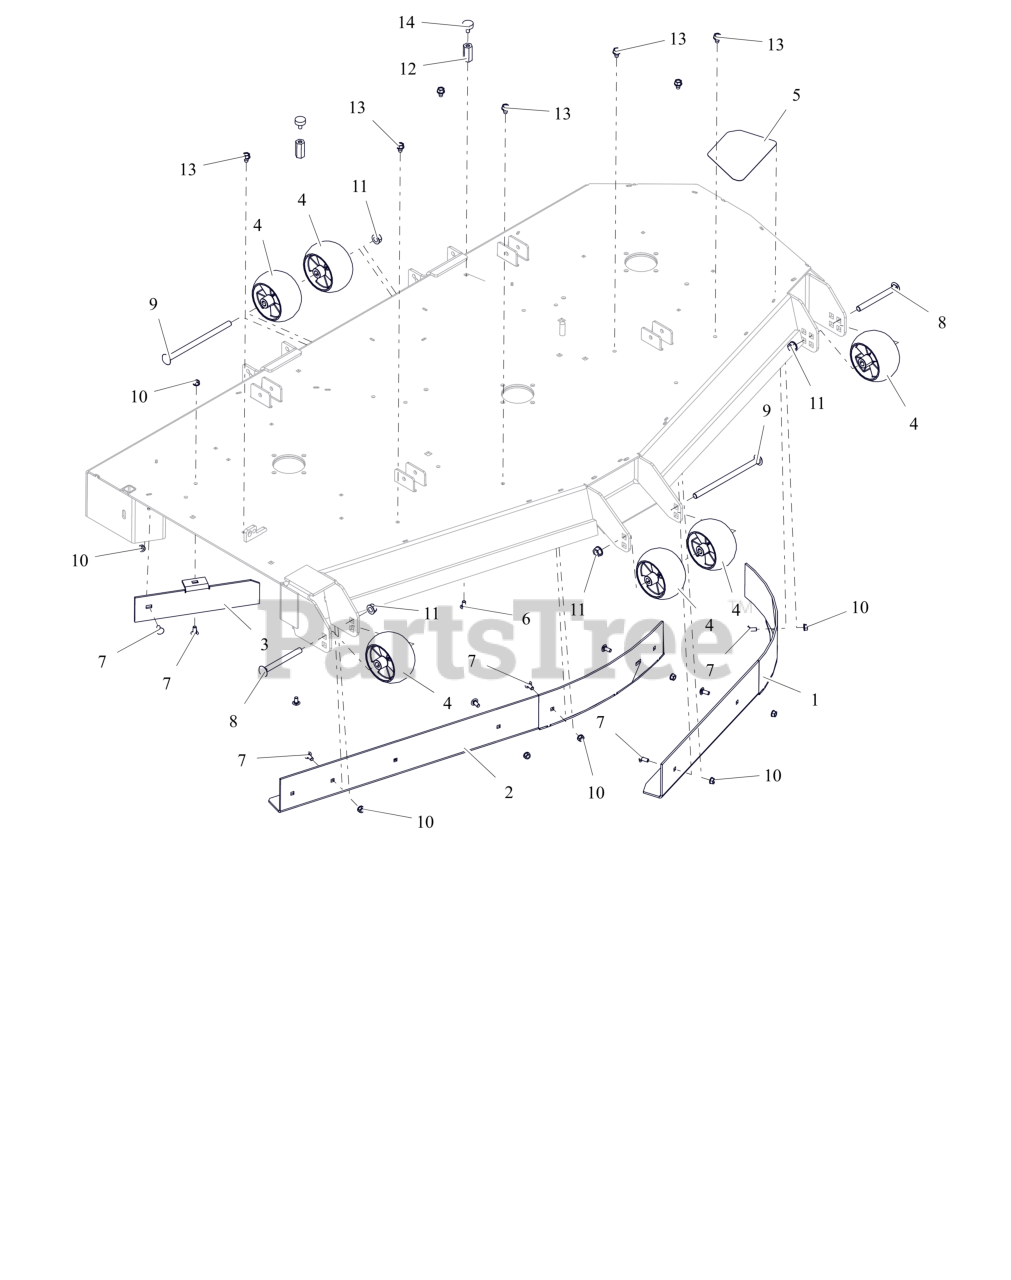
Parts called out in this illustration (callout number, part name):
1	WLDMT, 72" LH VACUUM BAFFLE (RED)
2	WLDMT, VACUUM BAFFLE 72" RH (RED)
3	72" DISCHARGE BAFFLE - RED
4	WHEEL, ANTI SCALP - 5X3 CTR W/RIBS
5	GRIP, STEP ANTI SKID
6	BTL,RHSSN .313-18 X 0.625 G5 ZCC
7	BLT, RHSSN.31-18X.750 G5 ZCC
8	BLT, RHSN .50-13X5.00 G5 ZCC
9	BTL,RHSN .500-13 X 8.5S G5 ZCC
10	NUT,LK-CTR-FLG .31-18 GF ZCC
11	NUT-LK-CTR-FLG .500-13 GG ZCC
12	NUT, COUPLING .312-18 X 1.625
13	SCR,TAP .375-16X.50 HWH TR ZCC
14	BUMPER, RUBBER
